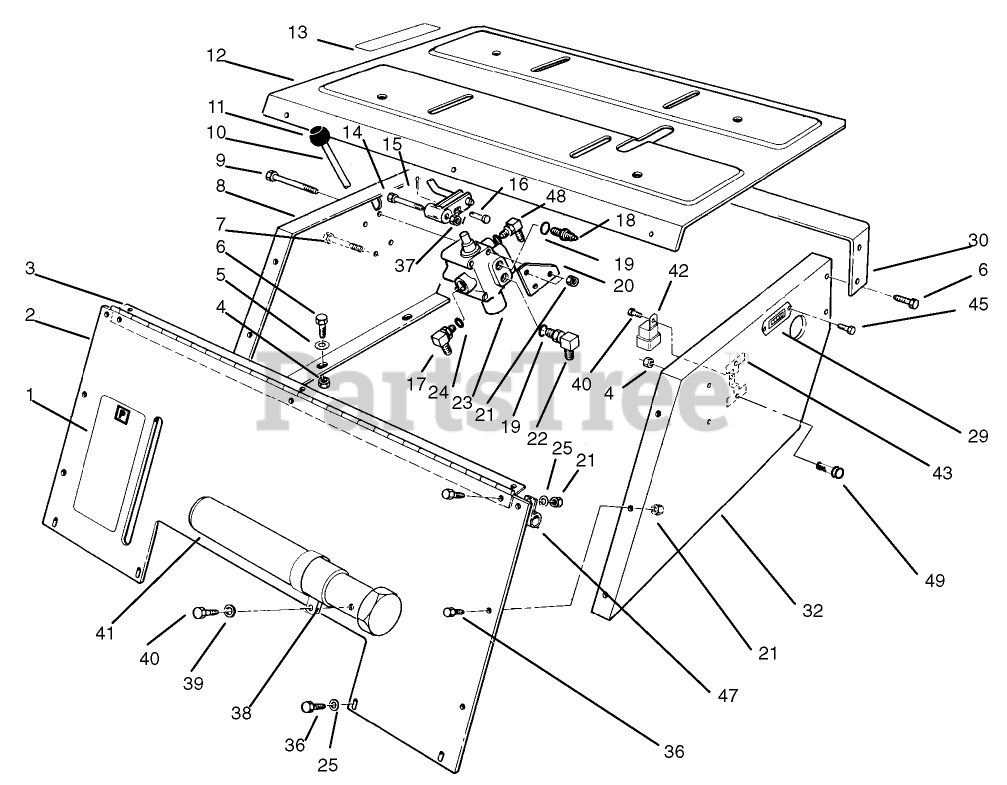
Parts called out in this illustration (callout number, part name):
1	PARK BRAKE DECAL
2	Support-Seat, Front
3	Hinge-Seat
4	NUT-LOCK, NI
5	WASHER-PLAIN
6	SCREW-HH
7	SCREW-HH
8	Support-Seat RH.
9	SCREW-HH
10	Lever-Valve
12	Plate-Seat
13	LIFT CONTROL DECAL
14	BOLT-WHEEL
15	PIN-COTTER
16	PIN-CLEVIS
17	FITTING-HYD, 90 DEG
18	FITTING-STRAIGHT
19	O-RING
20	LEVER BRACKET
21	NUT-LOCK, NI
22	FITTING-ELBOW, 90
23	VALVE ASM
24	O-RING
25	WASHER-FLAT
29	HOURMETER
30	Support-Hood
32	Support-Seat L.H.
36	SCREW-HH
37	NUT-LOCK, NI
38	CLAMP-R
39	WASHER-FLAT
40	SCREW-HWH
41	TUBE-MANUAL
42	RELAY
43	Bracket
45	SCREW-HWH
48	FITTING-ELBOW-90 DEG
49	SCREW-HH
